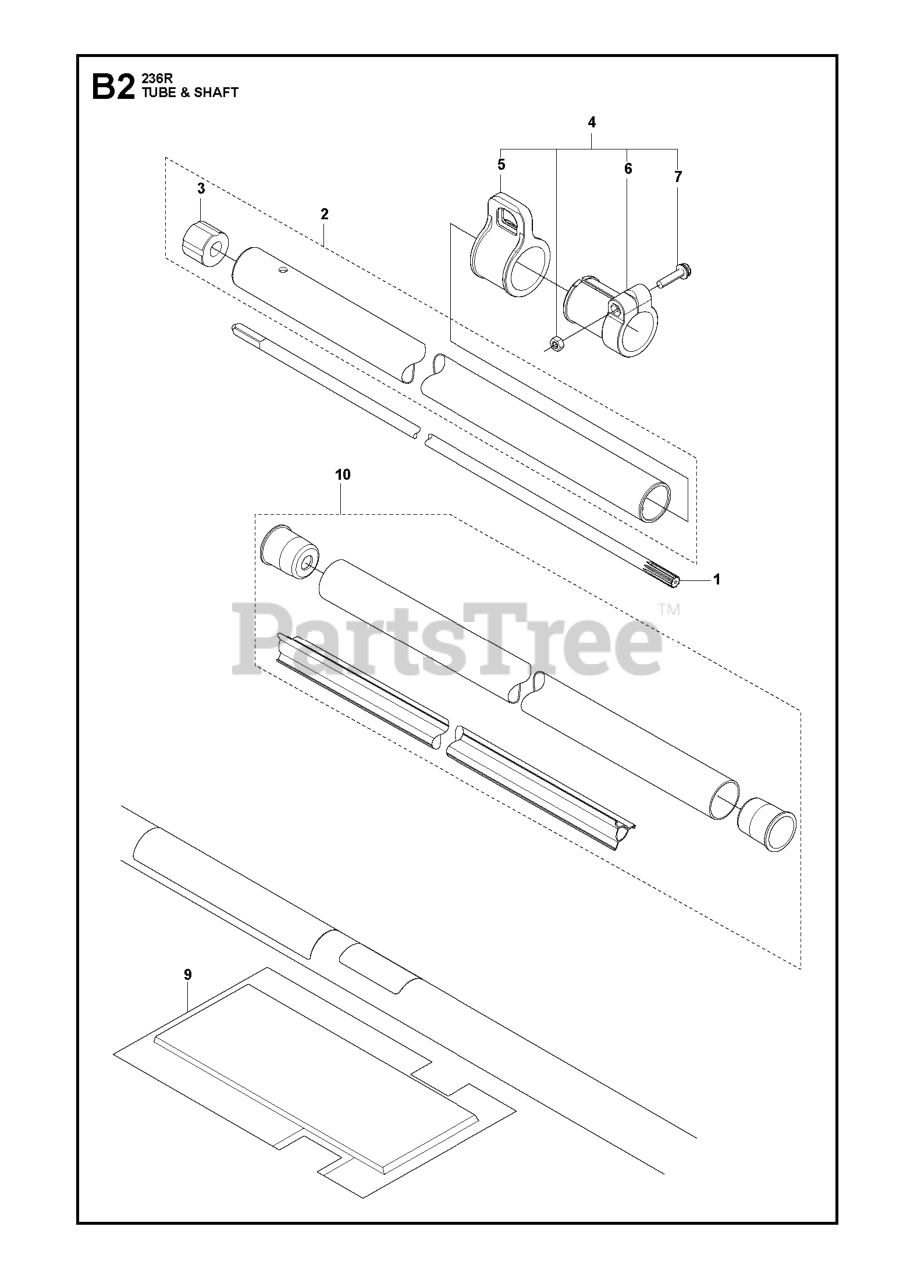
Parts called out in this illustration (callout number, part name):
1	DRIVE SHAFT
2	PIPE COMP.
9	PROTECTOR (RPLS 405017110)
